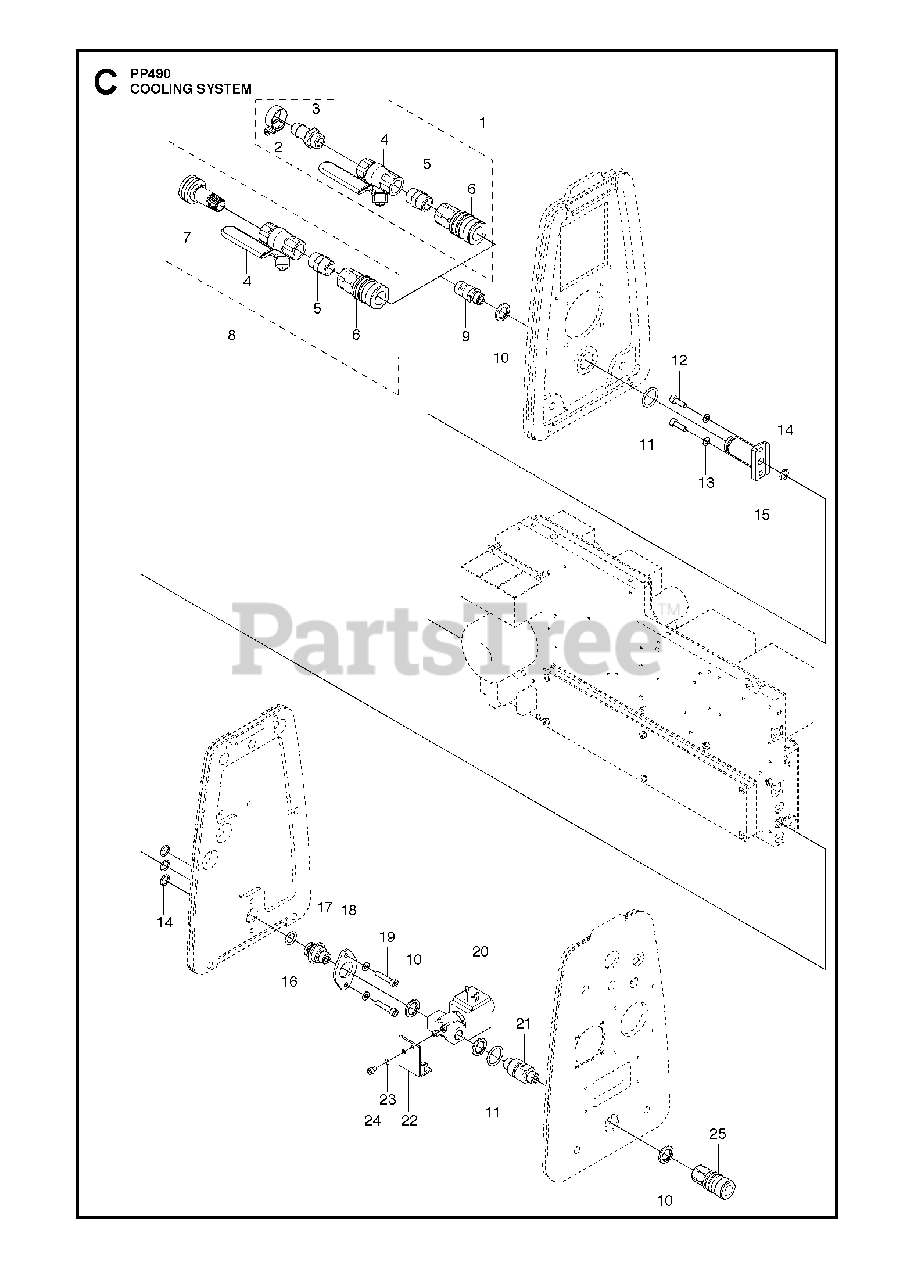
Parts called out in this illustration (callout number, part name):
10	SEALING WASHER
13	WASHER
19	SCREW IHSCM
